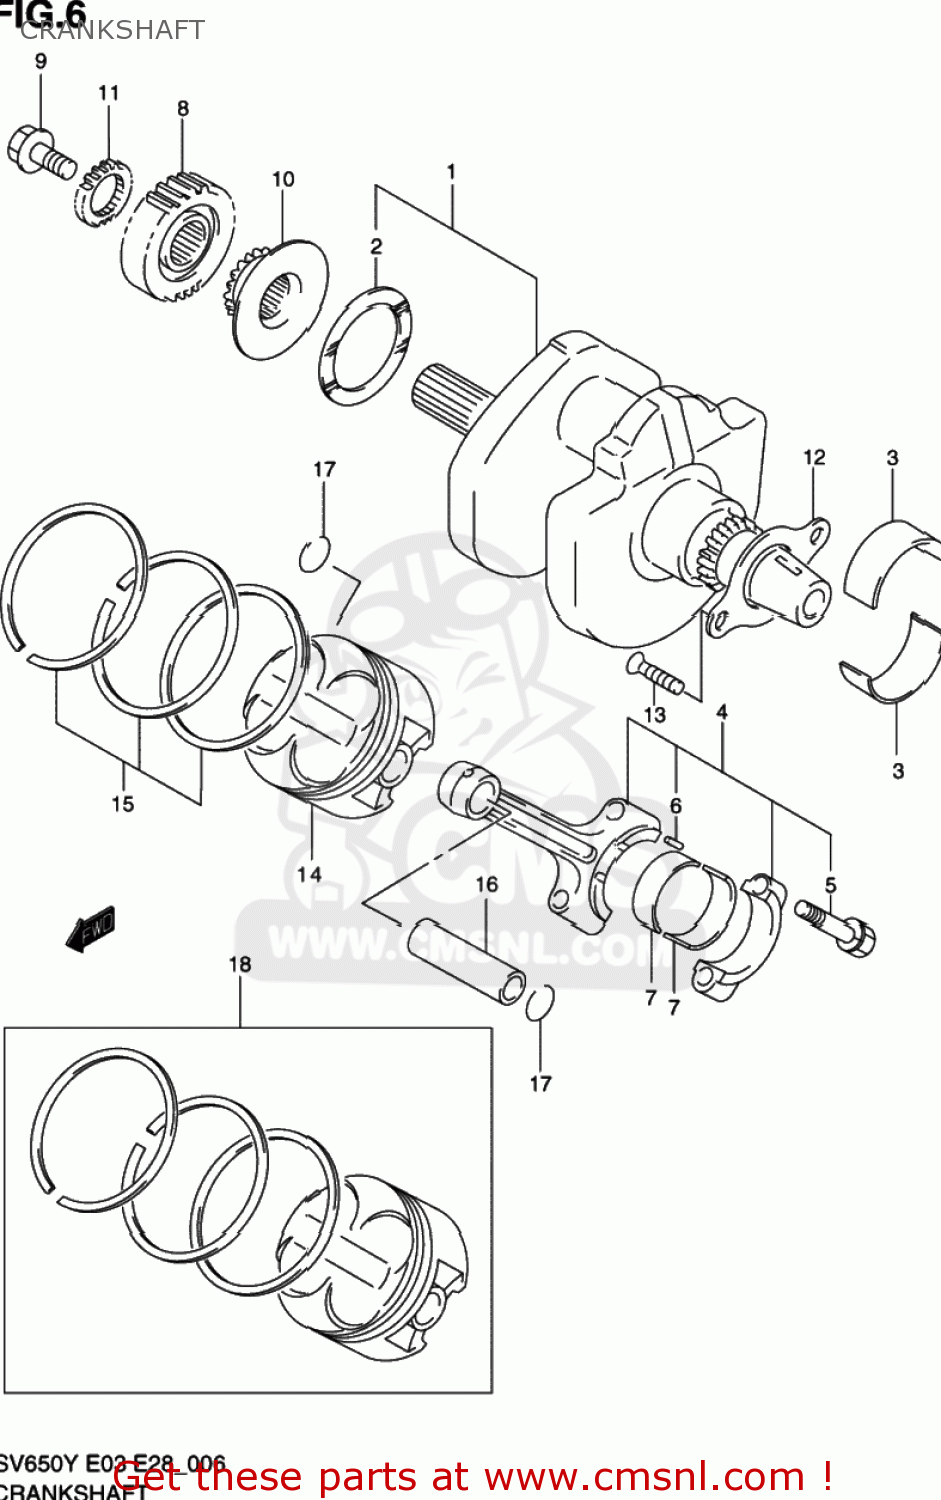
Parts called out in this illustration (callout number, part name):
1	CRANKSHAFT SET
2	WASHER,CRANK THRUST(T:2.0)
3	BEARING,CRANKSHAFT
4	CONNECTING ROD ASSY
5	BOLT,CONNCTING ROD
6	PIN,CONNECTING ROD
7	BEARING,CRANK PIN
8	GEAR,PRIMARY DRIVE
9	BOLT,PRIMARY DRIVE GEAR
10	SPROCKET,CAM CHAIN DRIVE
11	GEAR,WATER PUMP DRIVE
12	RTNR,CSHAFT BRG,L
13	SCREW(6X12)
14	PISTON
15	RING SET,PISTON
16	PIN,PISTON
17	CIRCLIP,PISTON PIN
18	PISTON SET(OS:0.5)
